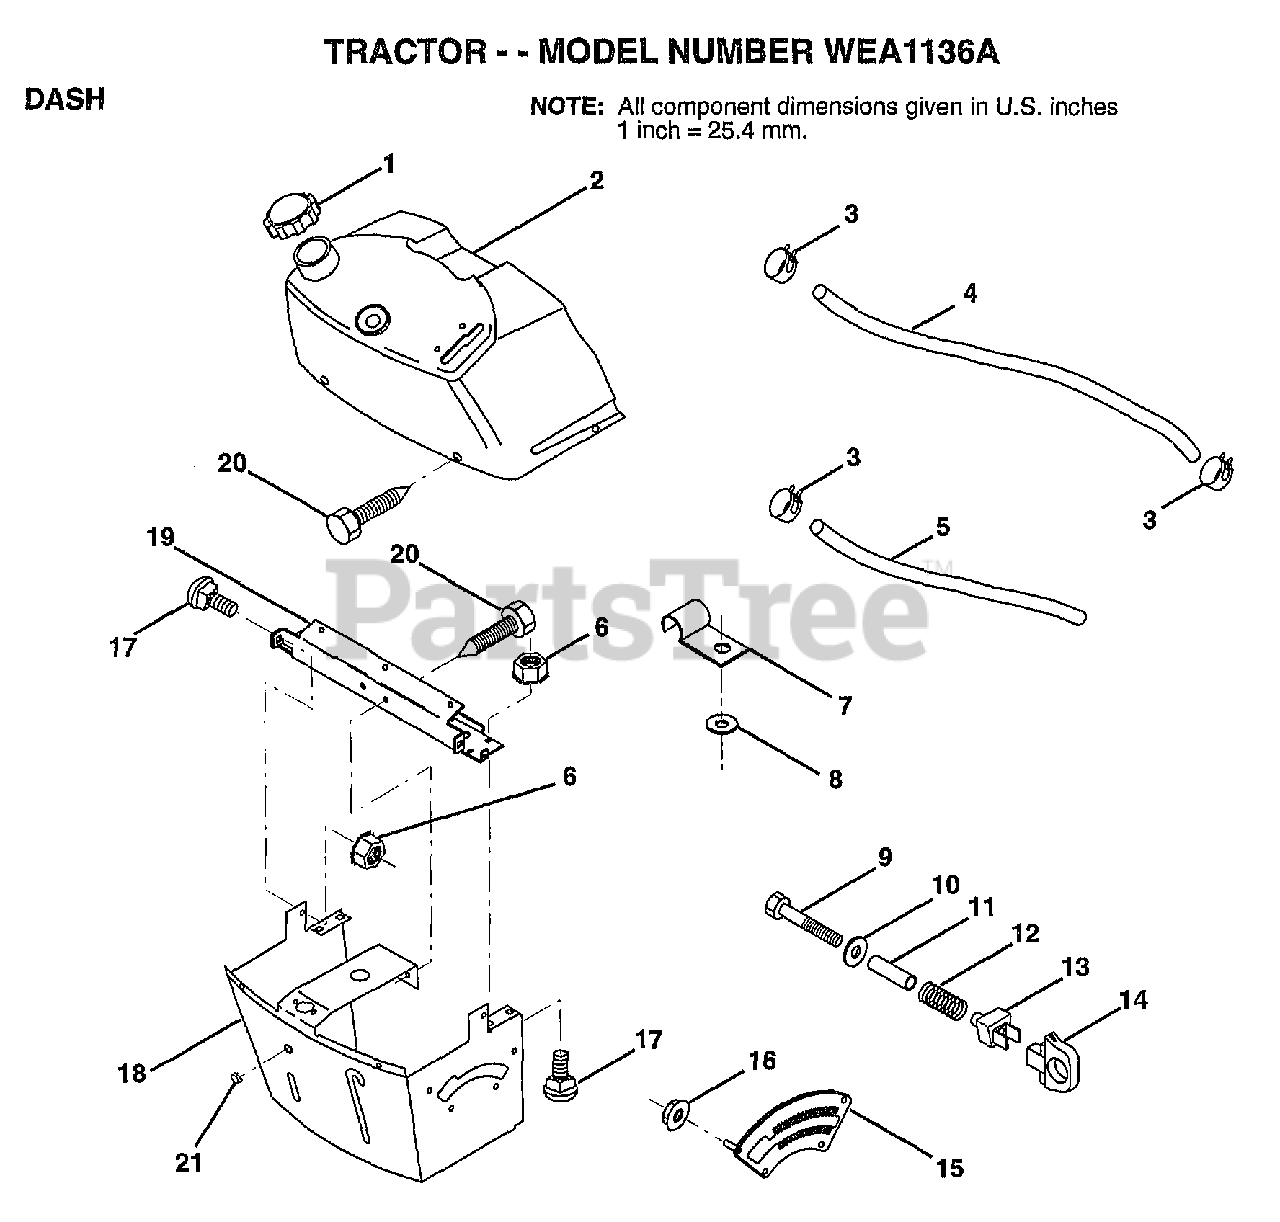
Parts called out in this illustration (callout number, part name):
1	CAP BLK FUEL LR
2	TANK.ASM.DASH.LR
3	HOSE CLAMP
5	FUEL LINE T
6	NUT HXKEP 1/4X20
7	CLIP T
8	WASHER PM
9	BOLT
11	SPACER SPLIT
12	SPRING M
13	"KNOB,HGT RETAINER"
14	KNOB
15	ADJUSTER QUAD
16	NUT
17	BOLT
18	SUPT ASSY DASH
19	CROSS BRACE
20	SCREW.1/4-20X1/2
21	PLUG DOME
